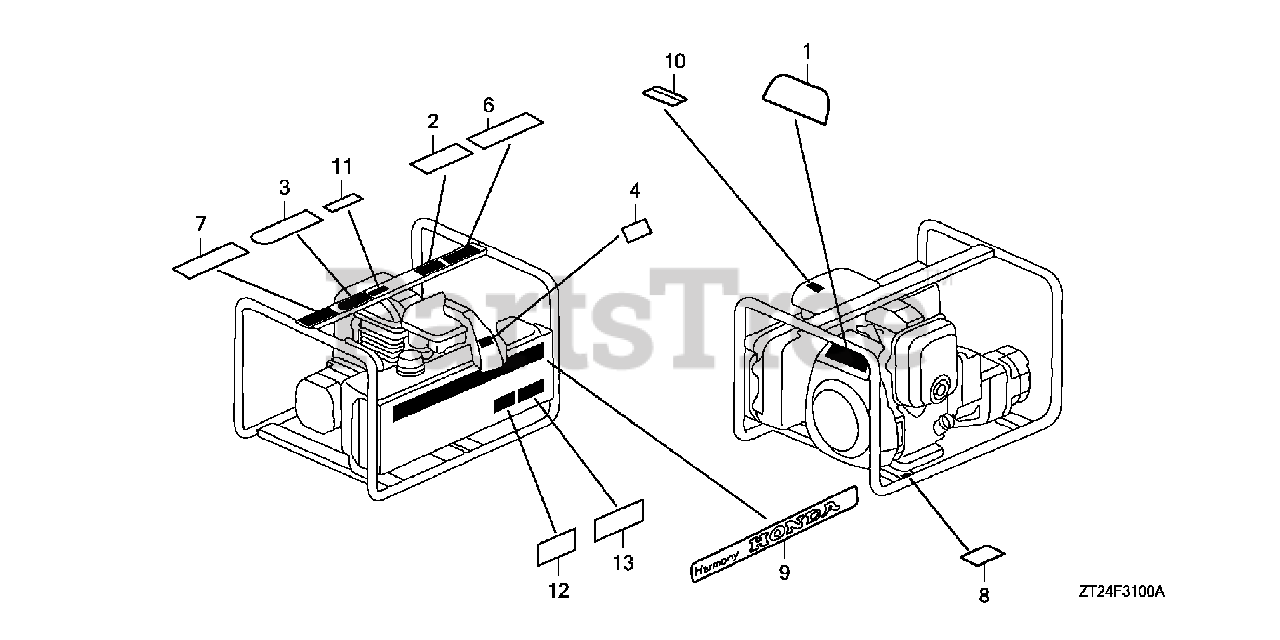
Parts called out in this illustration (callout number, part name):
1	PLATE, CAUTION (EN2000)
2	LABEL, RAIN WARNING (ENGLISH)
3	MARK, CAUTION (ENGLISH/FRENCH/SPANISH)
4	MARK, CHOKE
6	MARK, CAUTION (ENGLISH/FRENCH/SPANISH)
7	LABEL, CONNECT WARNING (ENGLISH)
8	MARK, OIL CAUTION
10	MARK, OIL ALERT (ENGLISH)
